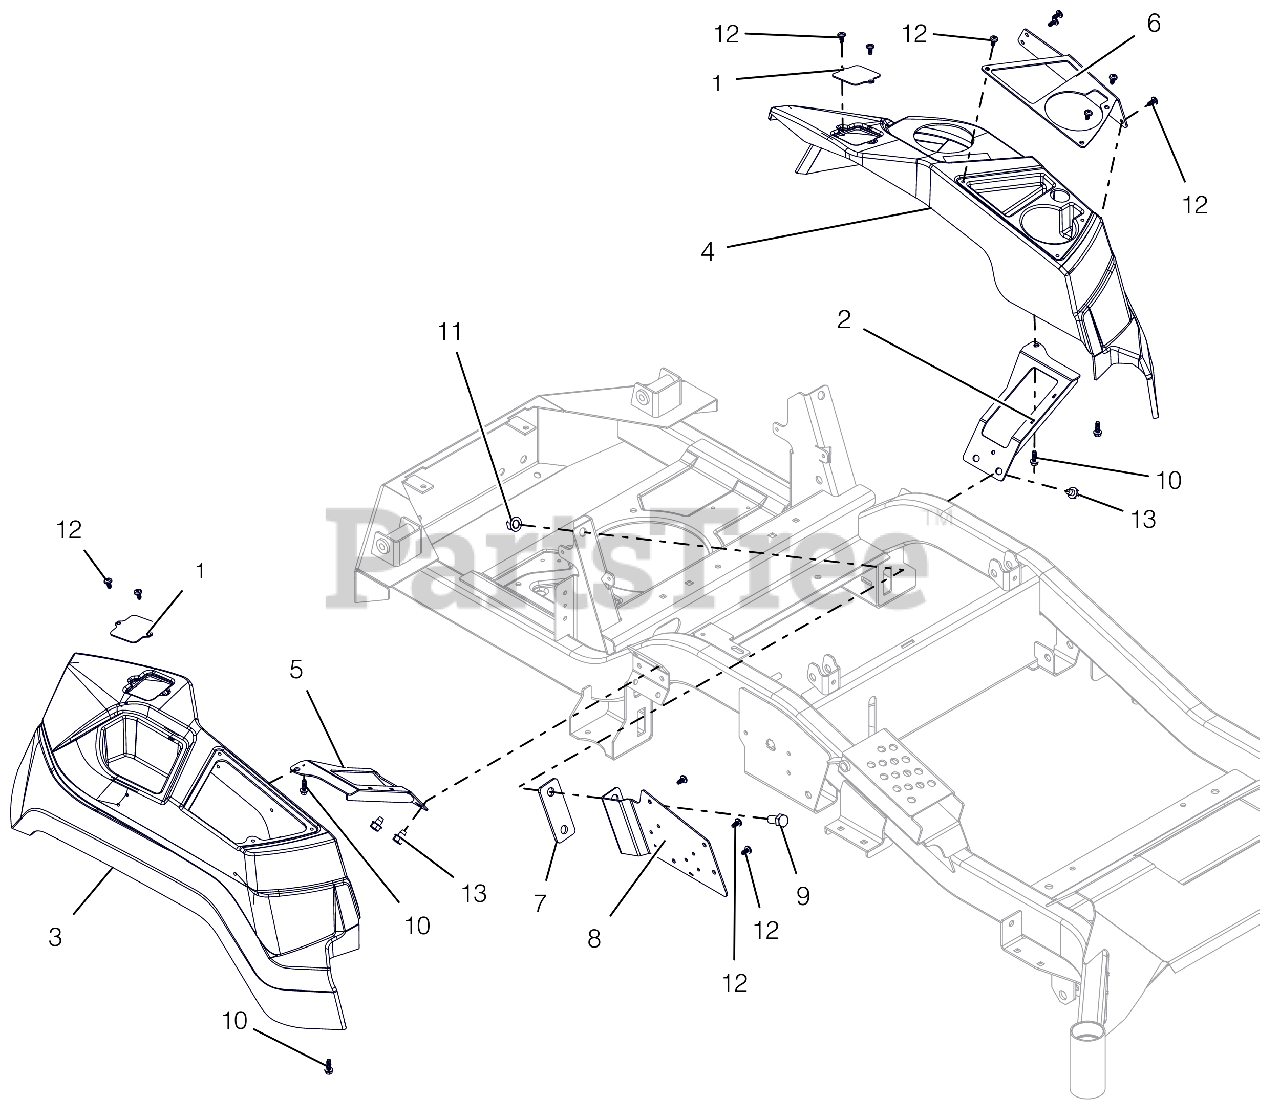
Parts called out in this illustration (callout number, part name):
1	PLATE, ROPS HOLE-HD
2	WLDMT, LH FENDER MOUNT
3	FENDER, RH APEX - 2017
4	FENDER, LH APEX - 2017
5	WLDMT, RH FENDER MOUNT
6	PLATE, APEX CUP HOLDER COVER
7	PLATE, CONTROL PANEL SPACER
8	BRKT, FENDER/RELAY MOUNTING
9	@BLT-HEX .50-13X1.00 GR5 YWZC
10	SCR-PLASTITE .25-10X.75, YWZC
11	@NUT-LK-TOP-FLG .50-13 YWZC
12	SCR-PAN .25-15X.50 6L H/LZB500
13	@SCR-TAP .38-16X.50 HWH TR YWZ
